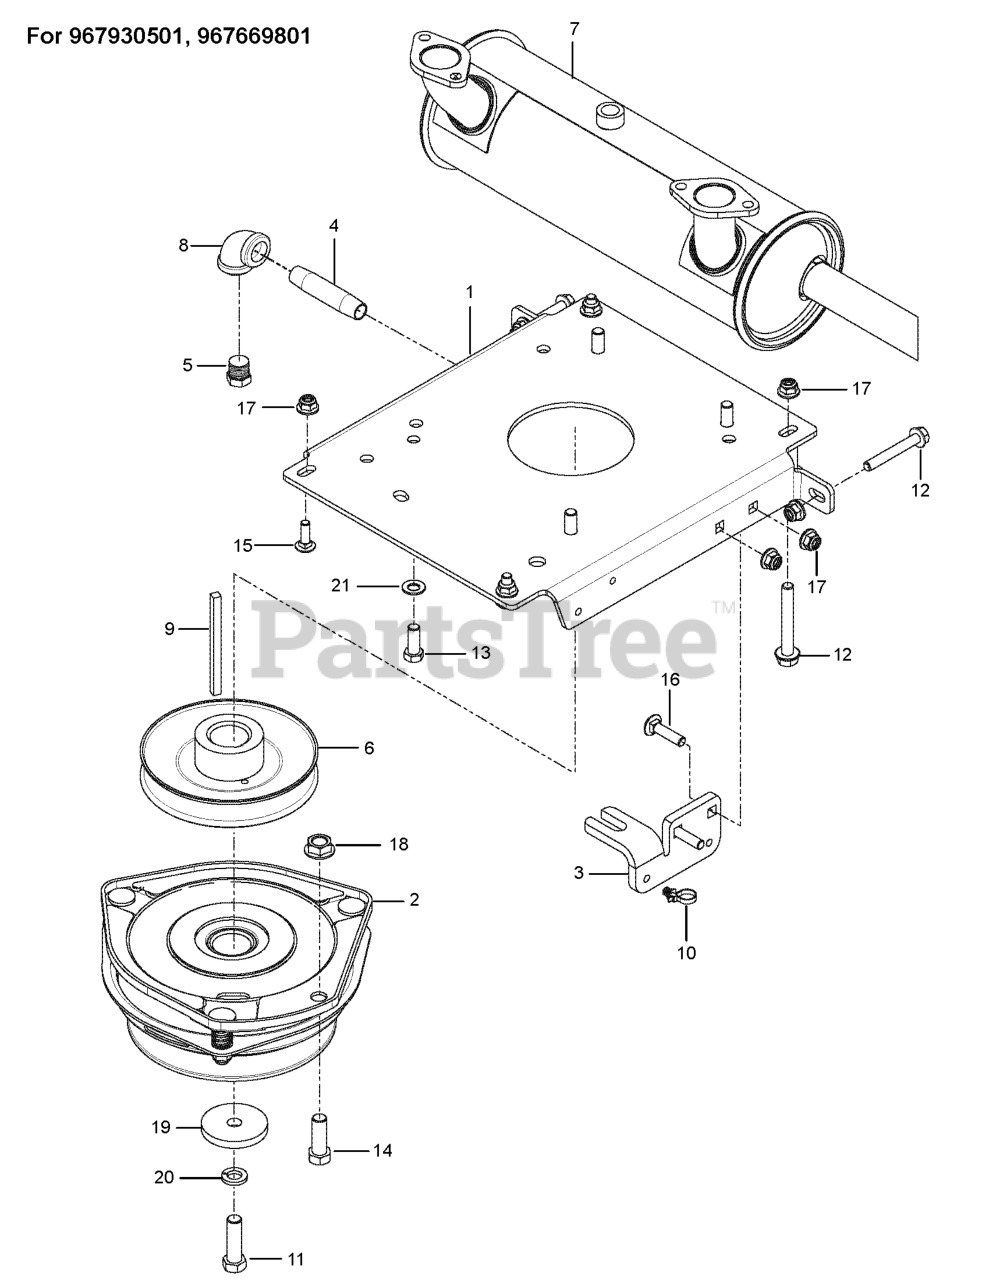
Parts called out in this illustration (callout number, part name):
1	PLATE.PNT.ENGINE.PZ/PZT.EDIP
2	CLUTCH, GT3.5
3	STOP, CLUTCH, OGURA
4	PIPE NIPPLE 3/8 X 3
5	PLUG, DRAIN 3/8 NPTF
6	PULLEY, ENGINE
7	MUFFLER YAMAHA PN: 7UD-E4711-
7	MUFFLER.KOH.EFI.824CC
8	90 DEG.ELBOW 3/8NPT
9	KEY, 1/4 SQ X 3.5
10	TIE WRAP, 8-3/8", W/CLIP
11	CLUTCH BOLT7/16-20X1.5GR5.96HR
12	HHFS 5/16-18 X 2.25 GD 5
13	HCS 3/8-16X1.GRD.5.ZD
14	BOLT FIN HEX 7/16-14 X 1
15	RHSNB 5/16C X 1
16	RHSNB 5/16-18 X 1-1/2 GR 5 ZD
17	5/16-18 NYLOC FLANGE NUT
18	NUT 7/16C WHIZ
19	BLADE WASHER
20	WASHER 7/16 LOCK
21	WASHER, 3/8 DISC SPRING SPEC
